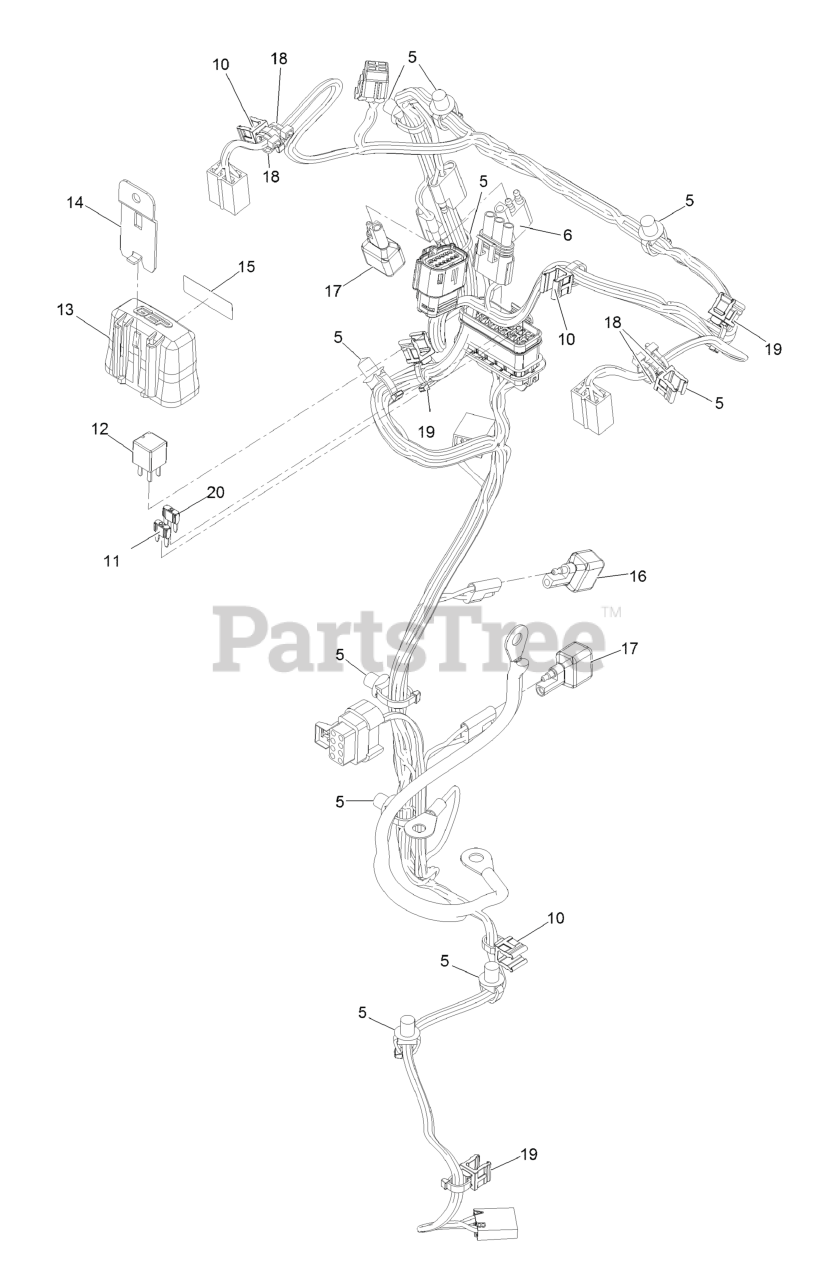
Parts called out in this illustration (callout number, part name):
5	CLIP-TIE
6	Cap-Plug
10	Clip-Edge
11	FUSE-MINI BLADE, 20 AMP
12	RELAY-MICRO
13	COVER-BLOCK, FUSE
14	CLIP-MOUNTING
15	DECAL-FUSE
18	TIE-CABLE
19	Clip-Edge W/Tie, Perpendicular
20	FUSE-MINI BLADE, 15 AMP
